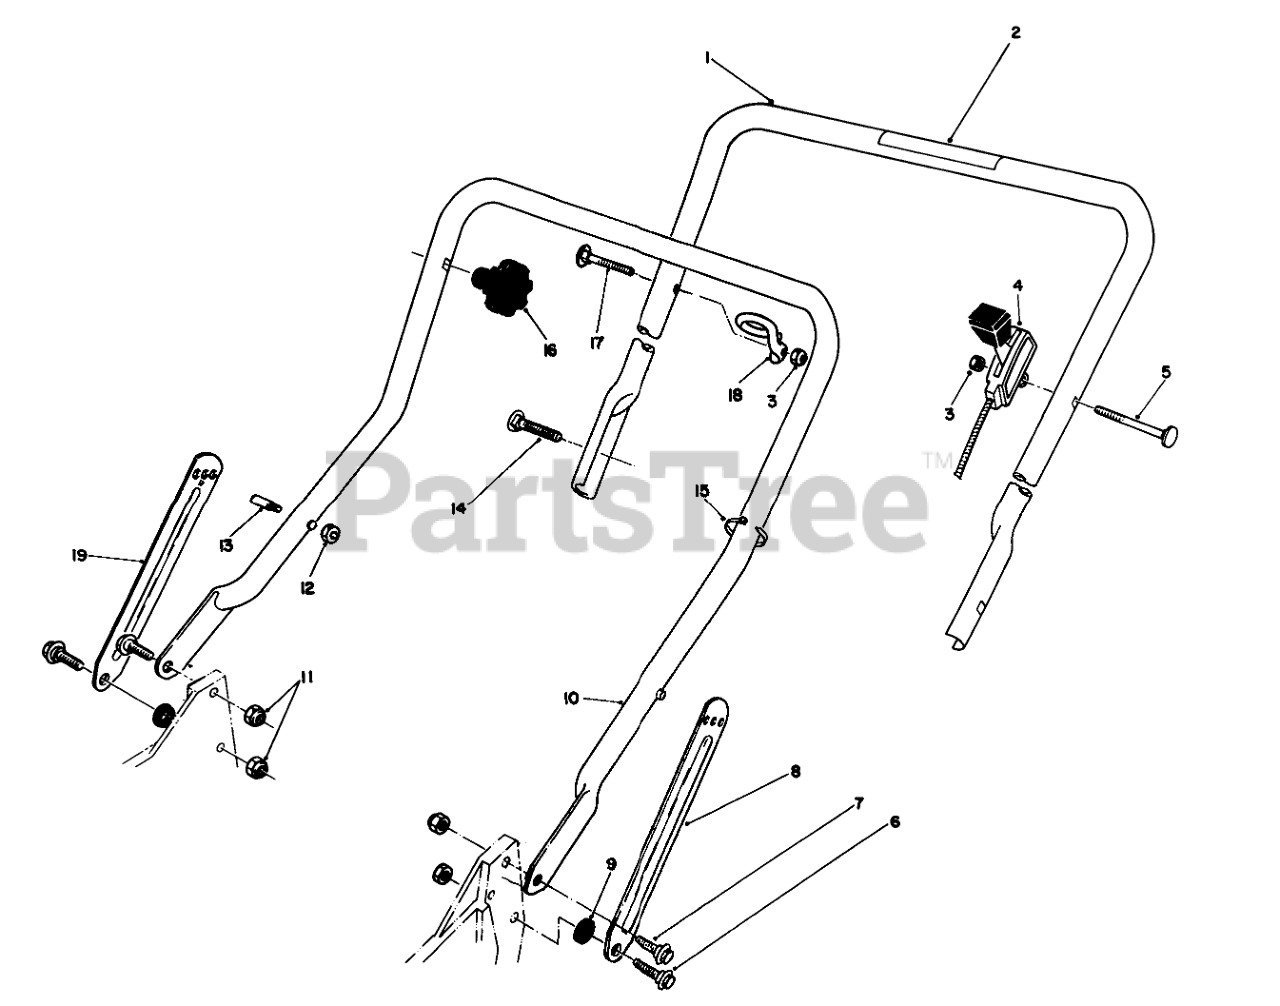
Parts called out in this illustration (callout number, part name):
1	Handle-Upper (Incl. Ref. #2)
2	DECAL - HANDLE
3	NUT-LOCK, NI
4	THROTTLE CONTROL
5	SCREW-HANDLE
6	SCREW-SHOULDER
7	SCREW-SHOULDER
8	LH HANDLE LATCH
9	SPACER
10	LOWER HANDLE ASM
11	NUT-LOCK, NI
12	NUT-LOCK, NI
13	HANDLE PIN
14	5/16-18 X 2 HNDLE SCREW
15	TIE-CABLE
17	HANDLE SCREW
18	Guide
19	RH HANDLE LATCH
